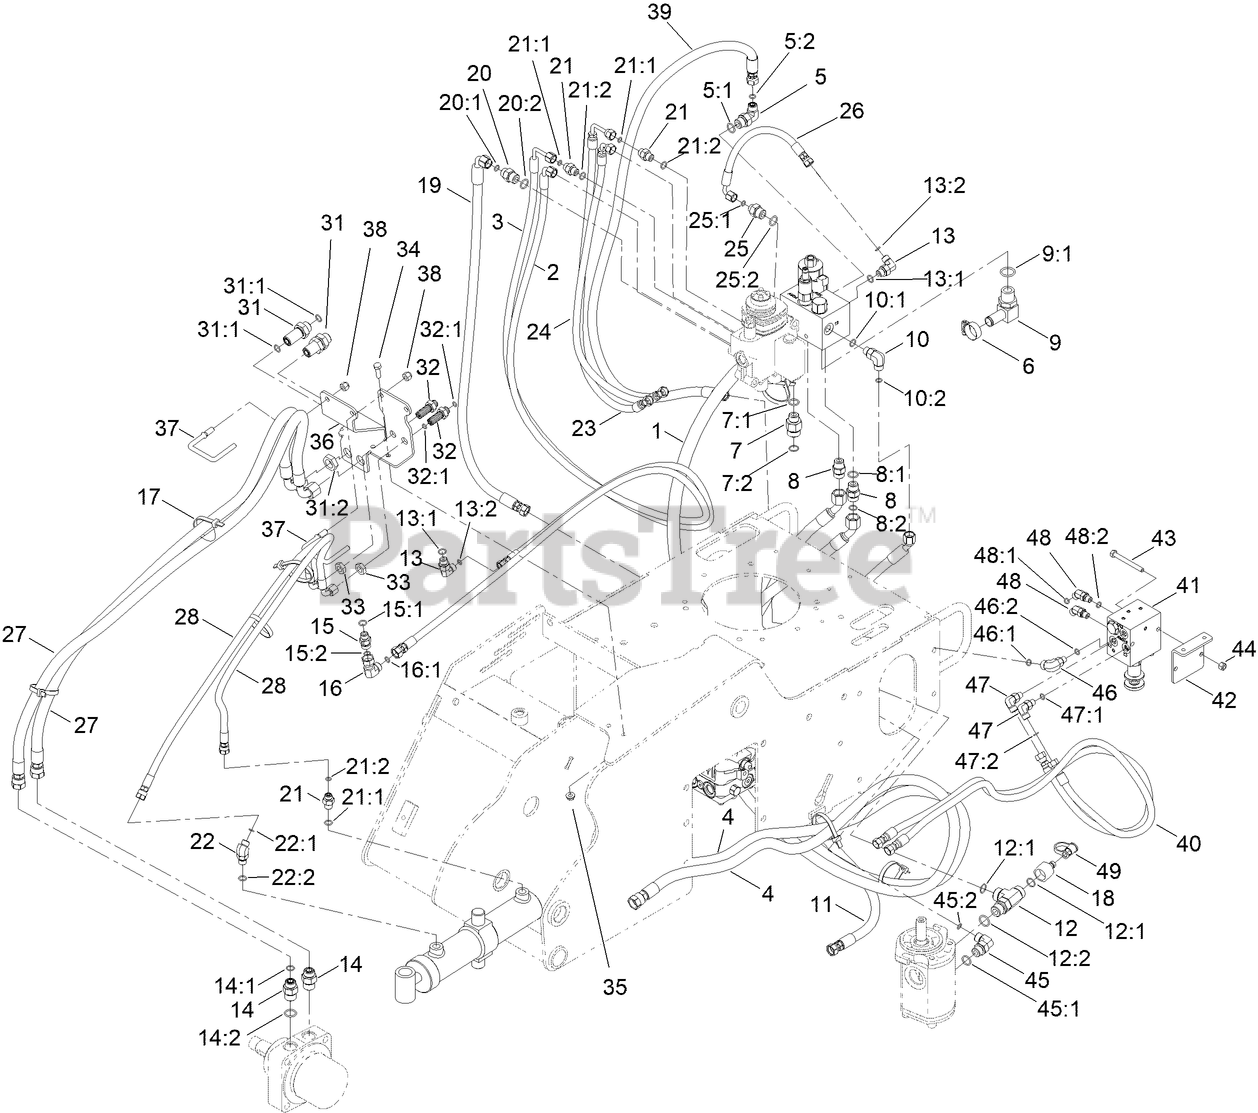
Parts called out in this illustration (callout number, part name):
1	HOSE-HYD
2	HOSE-HYD
3	HOSE-HYD
4	HOSE ASM-HYD
5	FITTING-HYD, 90 DEG
5:1	O-RING
5:2	O-RING
6	CLAMP-HOSE
7	FITTING-STRAIGHT
7:1	O-RING
7:2	O-RING
8	FITTING-STRAIGHT
8:1	O-RING
8:2	O-RING
9	FITTING-ELBOW, 90
9:1	O-RING
10	FITTING-ELBOW, 90 DEG
10:1	O-RING
10:2	O-RING
11	HOSE-HYD
12	FITTING-TEE
12:1	O-RING
12:2	O-RING
13	FITTING-ELBOW, 90 DEG
13:1	O-RING
13:2	O-RING
14	FITTING-STRAIGHT
14:1	O-RING
14:2	O-RING
15	VALVE-CHECK
15:1	O-RING
15:2	O-RING
16	FITTING-HYD, 90 DEG
16:1	O-RING
17	TIE-CABLE
18	NIPPLE
19	HOSE-HYD
20	FITTING-STRAIGHT
20:1	O-RING
20:2	O-RING
21	FITTING-STRAIGHT
21:1	O-RING
21:2	O-RING
22	FITTING
22:1	O-RING
22:2	O-RING
23	HOSE-HYD
24	HOSE-HYD
25	FITTING-STR
25:1	O-RING
25:2	O-RING
26	HOSE-HYD
27	HOSE ASM-HYD
28	HOSE ASM-HYD
31	FITTING-BULKHEAD
31:1	O-RING
31:2	NUT-BULKHEAD
32	UNION-BULKHEAD
32:1	O-RING
33	NUT-LOCK
34	SCREW-HH
35	NUT-HF
36	BRACKET-BULKHEAD
37	GUIDE-HOSE
38	NUT-LOCK, NI
39	HOSE-HYD
40	HOSE-HYD
41	SWEEP MANIFOLD ASM
42	BRACKET-VALVE
43	SCREW-HH
44	NUT-LOCK, NI
45	FITTING-HYD, 90 DEG
45:1	O-RING
45:2	O-RING
46	FITTING-ELBOW, 90 DEG
46:1	O-RING
46:2	O-RING
47	FITTING-ELBOW, 90 DEG
47:1	O-RING
47:2	O-RING
48	FITTING-HYD, 45 DEG
48:1	O-RING
48:2	O-RING
49	CAP-DUST
